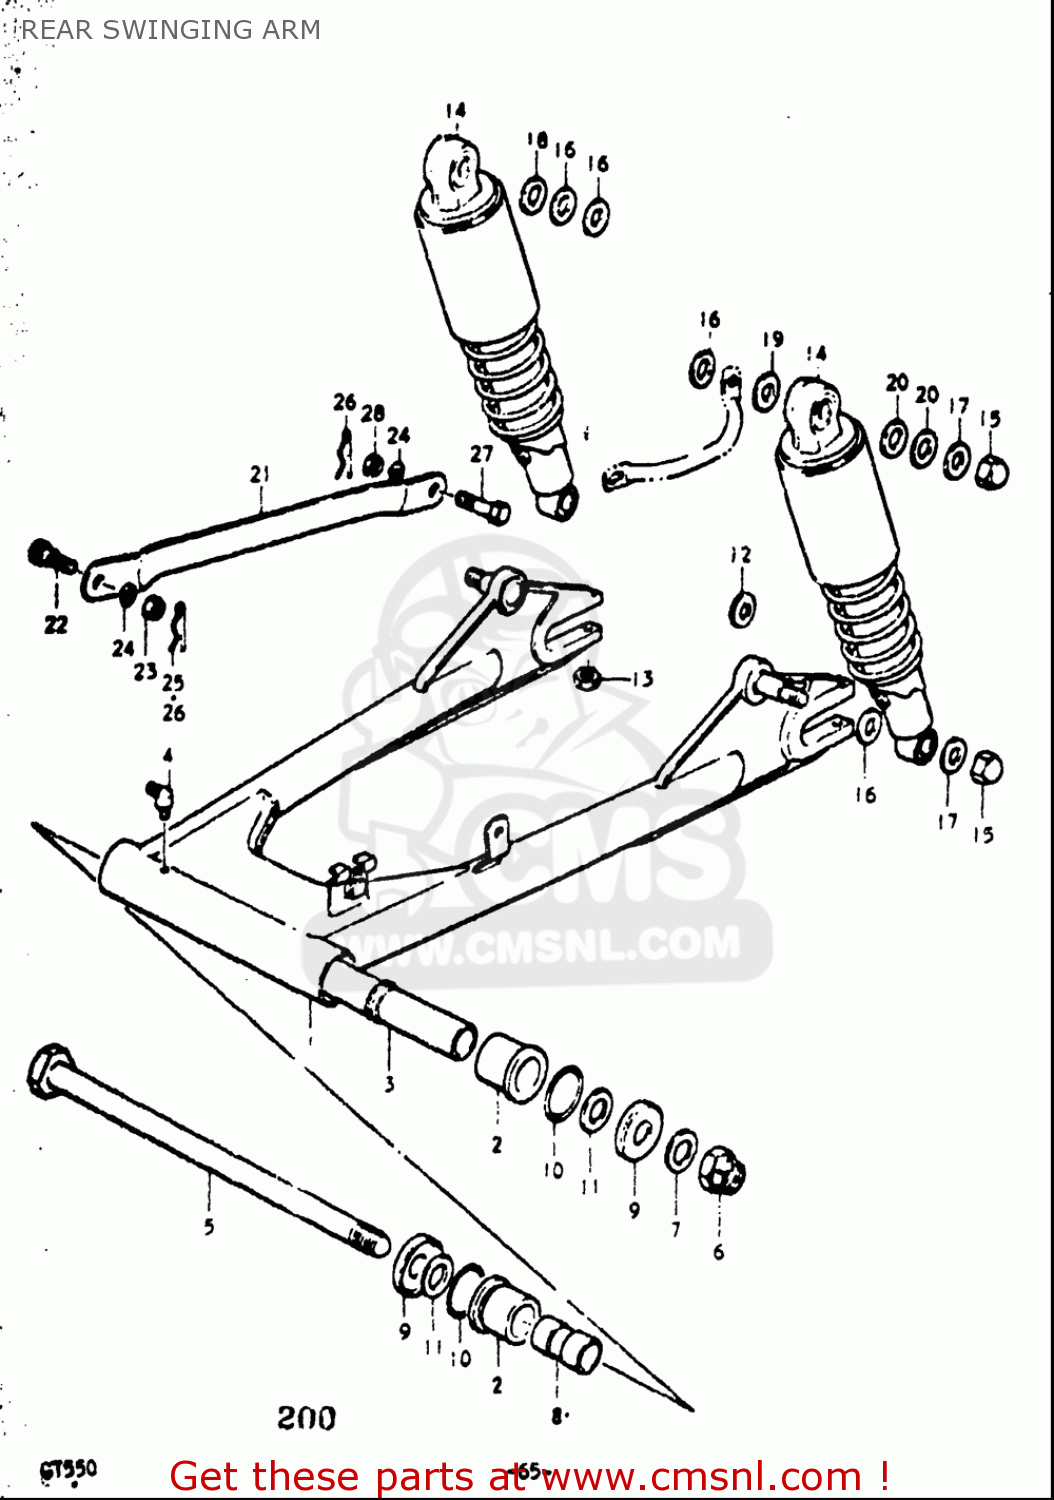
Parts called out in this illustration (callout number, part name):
2	BUSH
4	NIPPLE,GREASE
5	SHAFT,REAR SWING ARM
6	NUT 14MM
7	WASHER
8	SPACER
9	COVER
10	O RING(D:3,ID:29.5)
11	WASHER(14.5X29X2.3)
12	WASHER (8.2X22X3.2)
13	NUT
15	NUT
16	WASHER
17	WASHER (10.5X24X2.3)
18	WASHER(12.5X24X3.2)
19	WASHER(12.5X24X1.6)
20	WASHER (10.5X25X3.2)
22	BOLT(10X24.5)
23	NUT
24	WASHER,LOCK
25	CLIP
26	BOLT(10X31)
27	NUT
